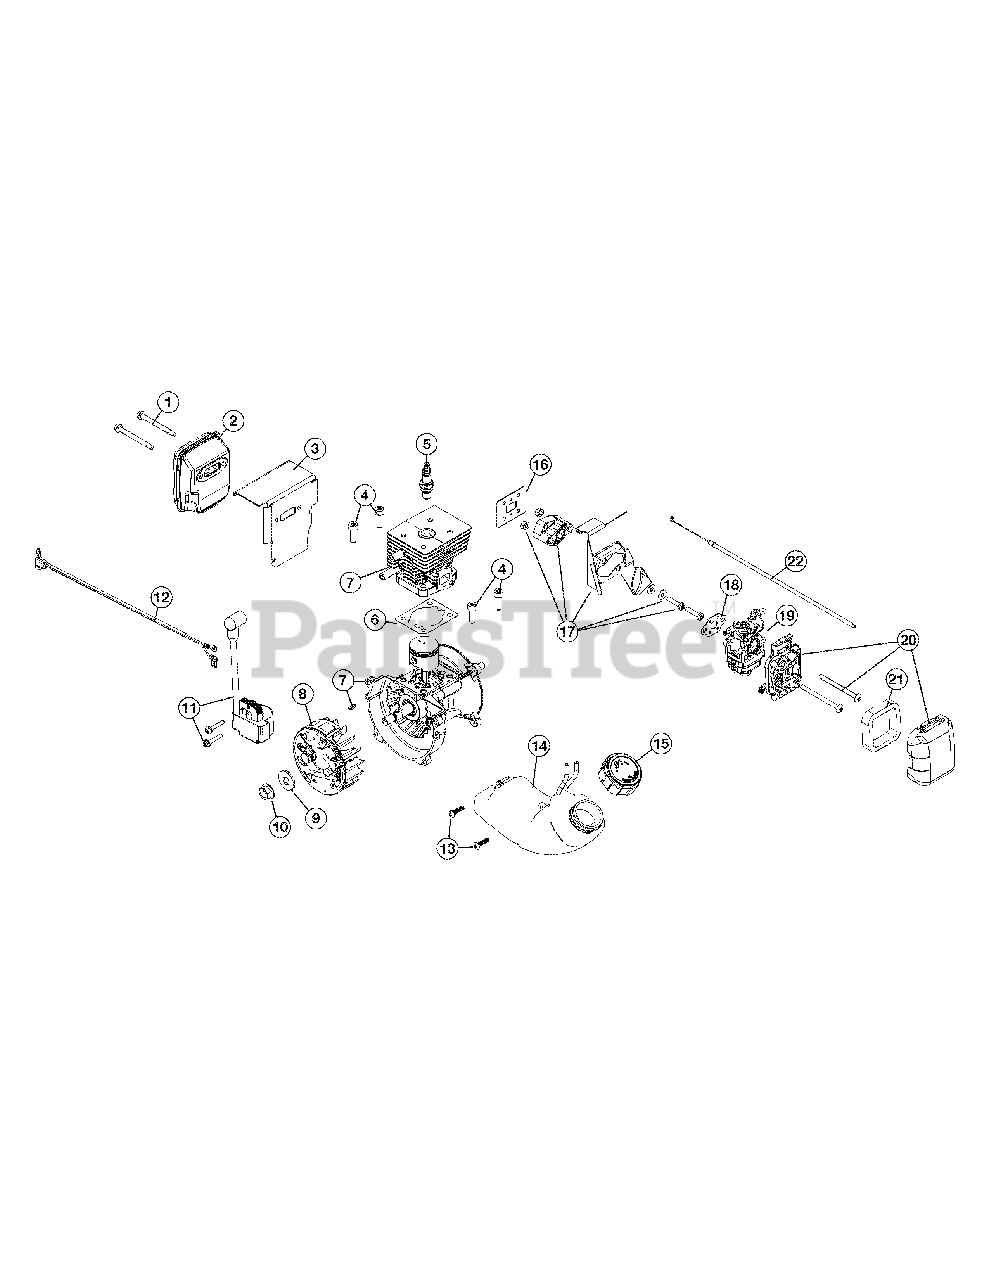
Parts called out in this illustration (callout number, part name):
1	Muffler Screws
2	Muffler Assembly (Incl. Ref No. 1 & 3)
3	Muffler Gasket
5	Spark Plug
6	Cylinder Gasket
7	Shortblock Assembly (Incl. Ref No. 4-6 & 8-11)
8	Flywheel Assembly
11	Module Assembly
14	Fuel Tank Assembly (Incl. Ref No. 13 & 15)
16	Insulator Gasket
17	Insulator Assembly (Incl. Ref No. 16)
18	Carburetor Gasket
19	Carburetor Assembly (Incl. Ref No. 18)
20	Aircleaner Assembly (Incl. Ref No. 21)
22	Throttle Cable
